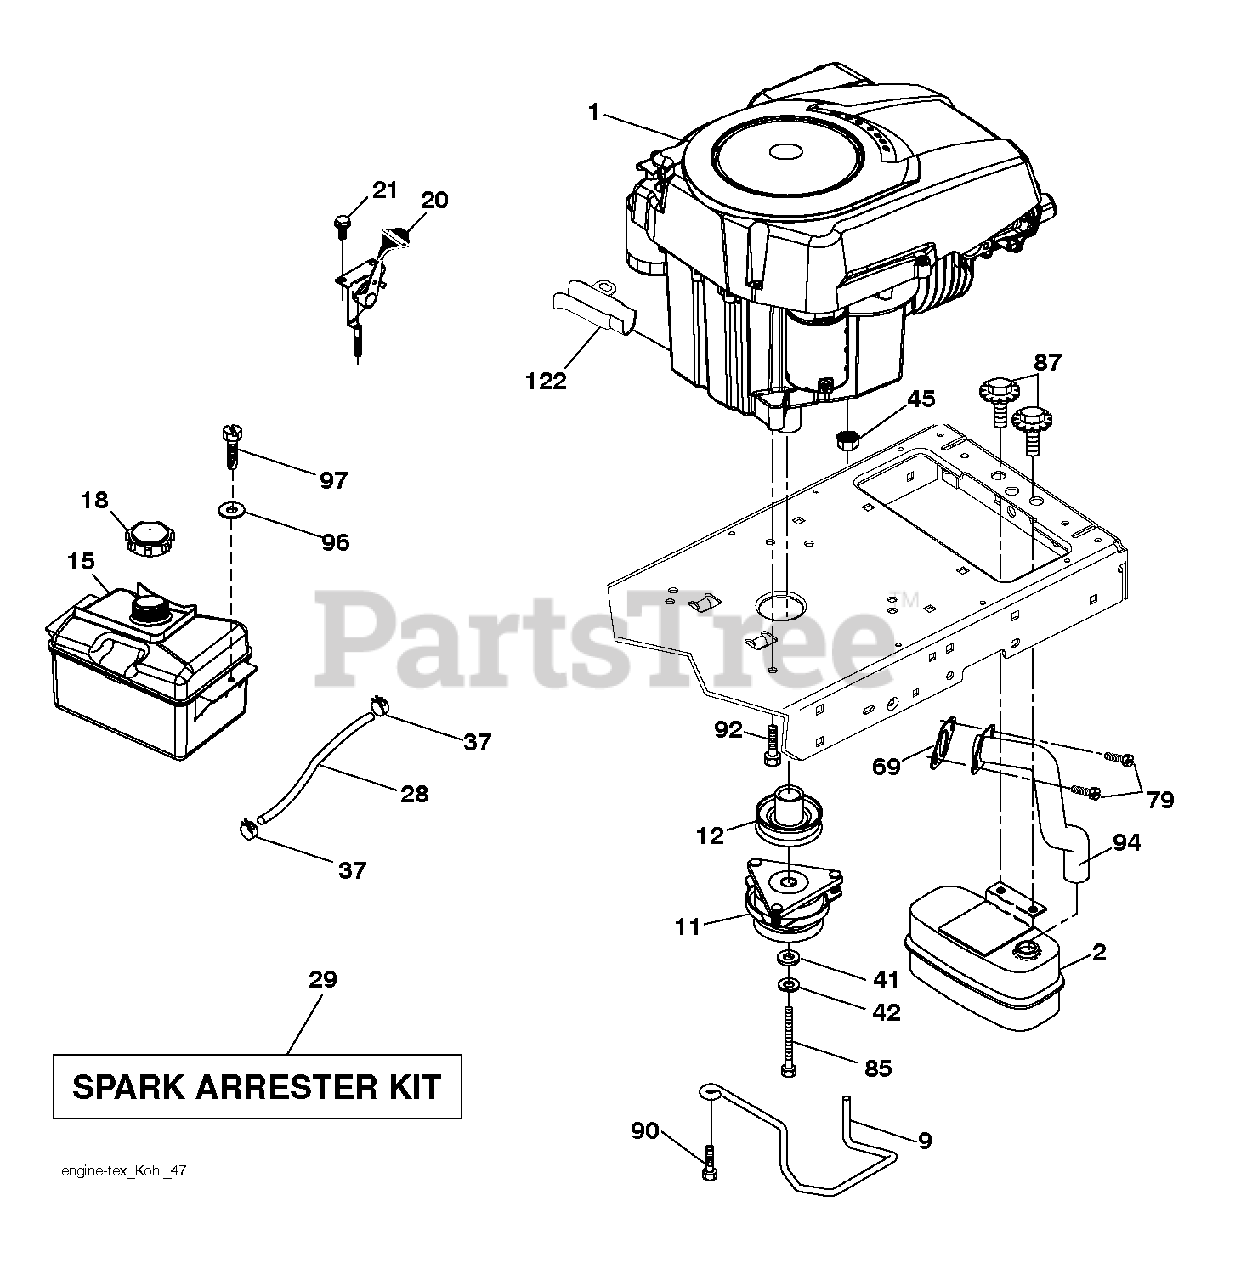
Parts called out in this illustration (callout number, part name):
2	MUFFLER.SINGLE.LRG.BRIGGS.KOHL
9	KEEPER BELT ENGINE
11	RB.CLUTCH.OGURA.4.4.PD
12	PULLEY.ENGINE.TUFFTORQ
15	FUEL.TANK.ASM.NON-EPA
18	CAP ASM.FUEL.2.25"FR.
20	CONTROL.TH/CK.C.
21	SCREW.#10 X 0.750.BOS
28	LINE.FUEL.20
29	KIT.SPARK ARRESTOR 794945 B&S
37	HOSE CLAMP
42	LOCKWASHER
45	NUT
69	GASKET.EXHAUST.KOHLER
79	SCREW.SOCKET HD.5/16-1
85	BOLT HEX 7/16-20X4-1/4"
87	BOLT, 5/16-18 X 1 3/4
90	SCREW 3/8-16X1
92	SCREW 3/8-16X1
94	TUBE.EXHAUST.KOHLER.COURAGE
97	SCREW HEXWSHR 1/4-20X3/4
122	EXTENSION DRAIN OIL
